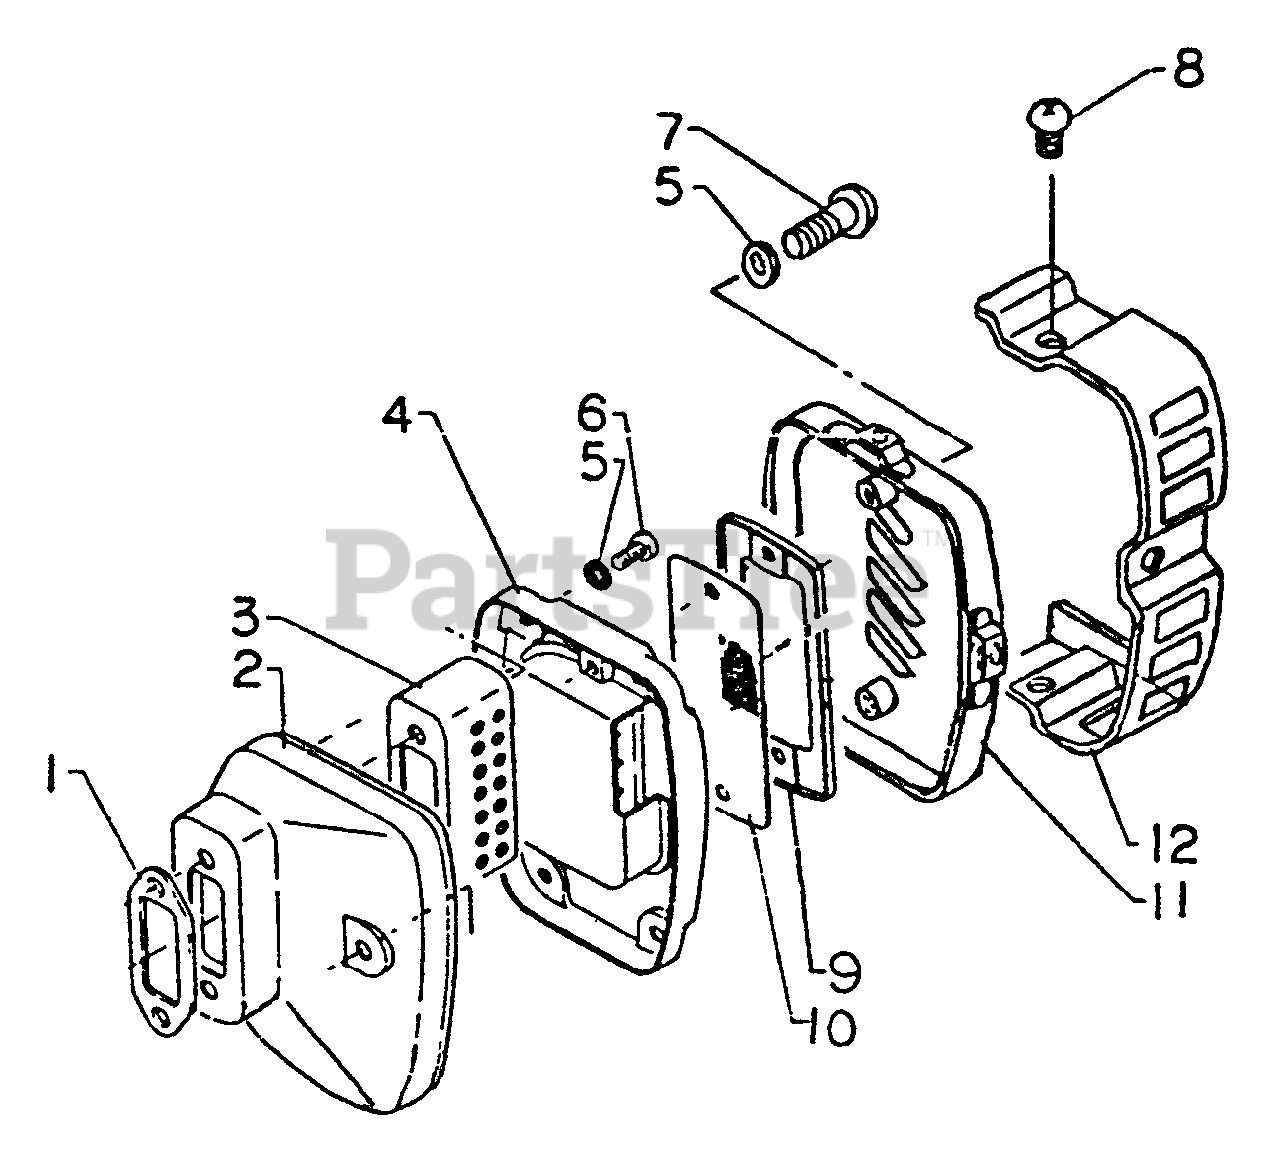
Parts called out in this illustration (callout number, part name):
1	GASKET, EXHAUST
2	MUFFLER
3	BAFFLE, MUFFLER
4	LID, MUFFLER
5	LOCKWASHER - 5
6	SCREW - 5X8
7	SCREW - 5X16
8	SCREW - 4X6
9	RETAINER, SCREEN
10	SCREEN, SPARK ARRESTOR
11	LID, MUFFLER
12	COVER, EXHAUST
